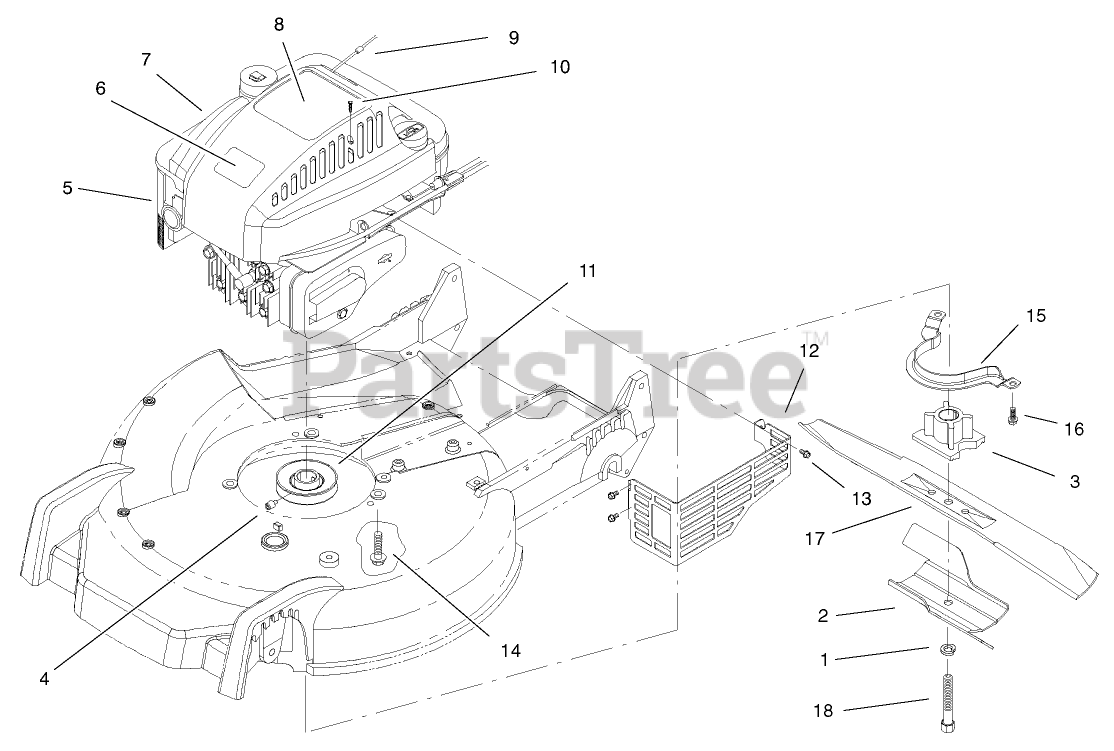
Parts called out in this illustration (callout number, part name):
1	WASHER-LOCK
2	ACCELERATOR-BLADE
3	RETAINER-BLADE
6	DECAL
7	SHROUD-ENGINE
8	DECAL - RECOIL
9	STOP-ROPE
11	PULLEY
12	SHIELD-MUFFLER
13	SCREW-TAPTITE
14	SCREW-HWH
15	BRACKET-GUIDE, BELT
16	SCREW-HWHTF
